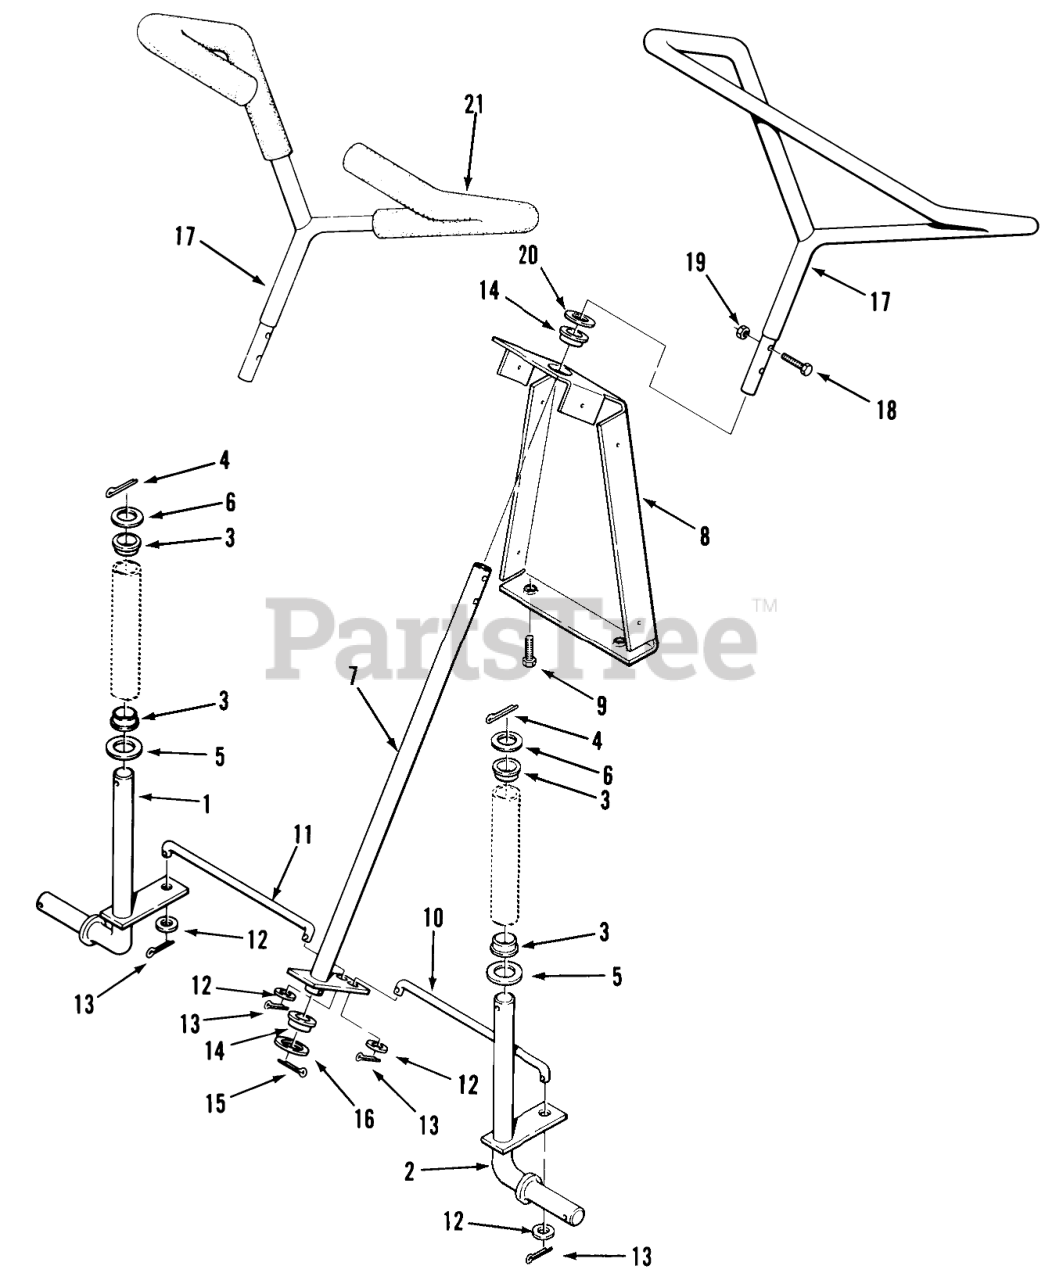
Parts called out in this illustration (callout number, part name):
1	SPINDLE ASSY RH R
2	SPINDLE ASSY LH R
3	BUSHING
4	Cotter Pin
5	Washer
6	WASHER
7	Steering Shaft Assy
8	SUPPORT-STG UPPER B
9	Screw
10	LH TIE ROD R
11	RH TIE ROD R
12	Washer-3/8
13	Cotter Pin
14	BEARING
15	Cotter Pin
16	WASHER-FLAT
17	Steering Wheel
18	Bolt
19	Nut
20	Washer
21	Grips-Steering Wheel 112-6
